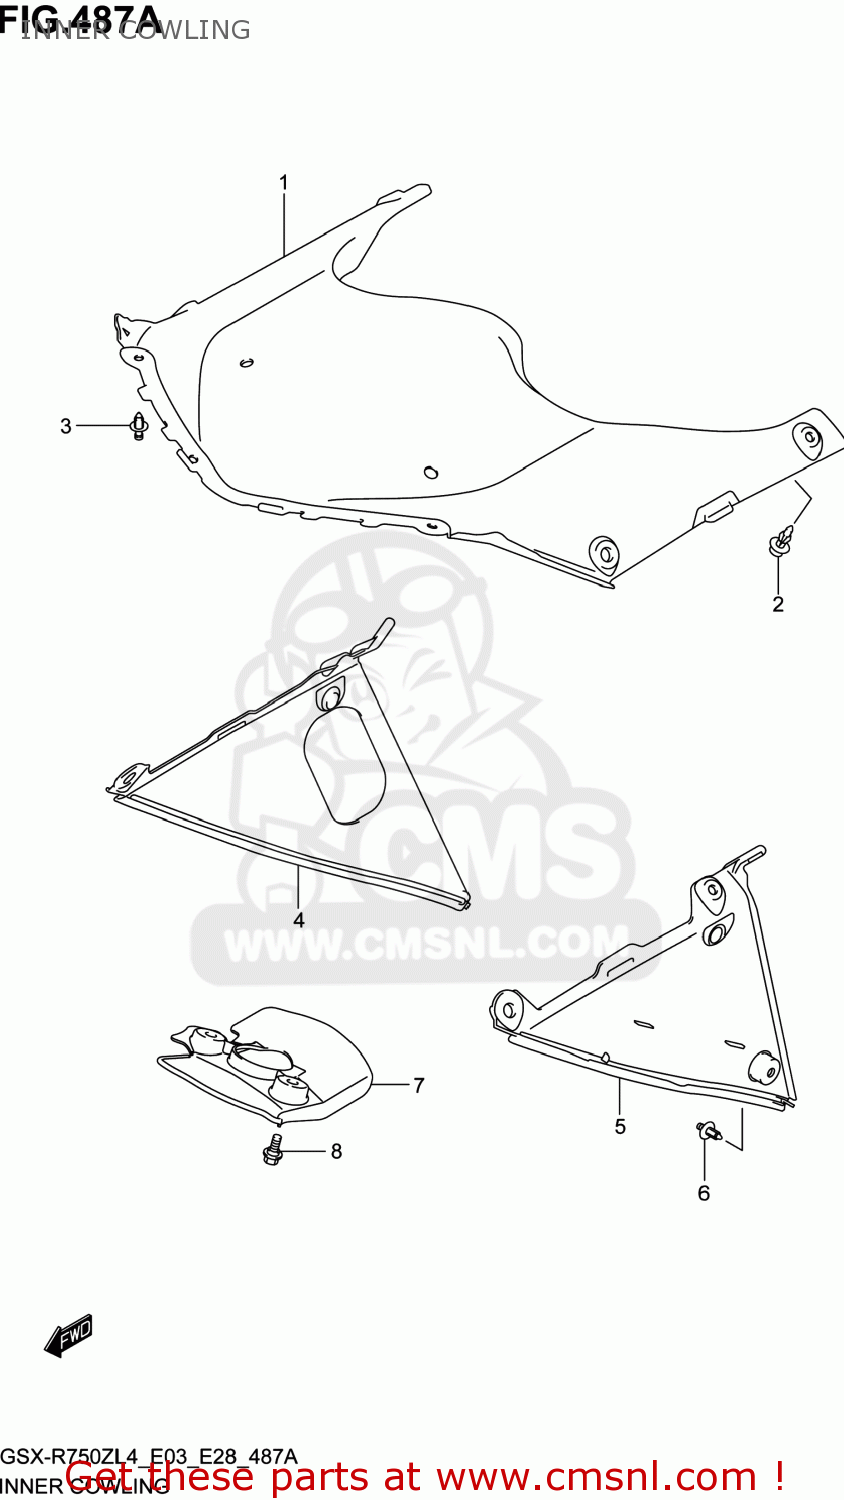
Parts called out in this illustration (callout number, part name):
1	COVER,BODY COWLING
2	CLIP(BLACK)
3	CLIP(BLACK)
4	COWLING,UNDER INNER,R
5	COWLING,UNDER INNER,L
6	CLIP
7	COVER,LWR BRACKET
8	BOLT(6X12)
